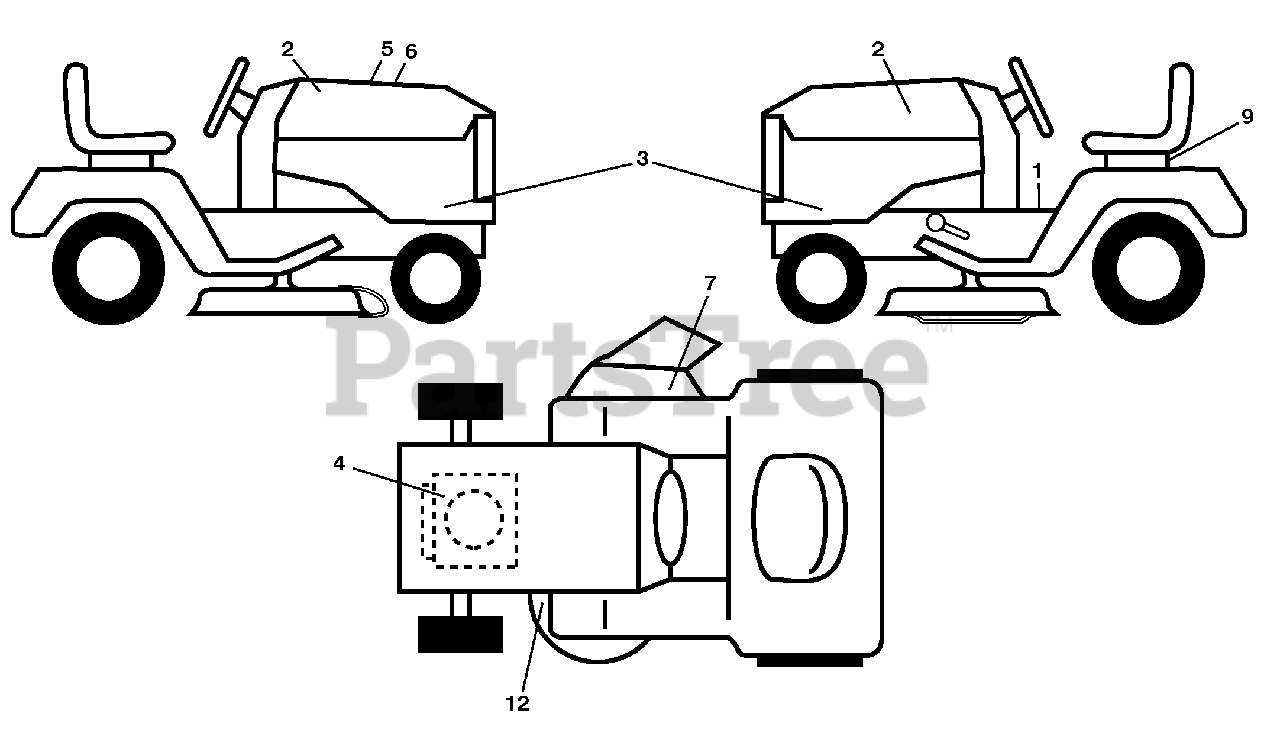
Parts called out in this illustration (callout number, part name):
1	Decal, Fender Warning
2	Decal, Hood
3	Decal, Hood Panel SD
4	Decal, Engine H.P.
5	Decal, Customer Respons.
6	Decal, Replacement
7	Decal, Mower Warn. Keep Hands Away
9	Decal, Battery Dnge/Poi
12	Decal, Mower V-Belt Schematic
